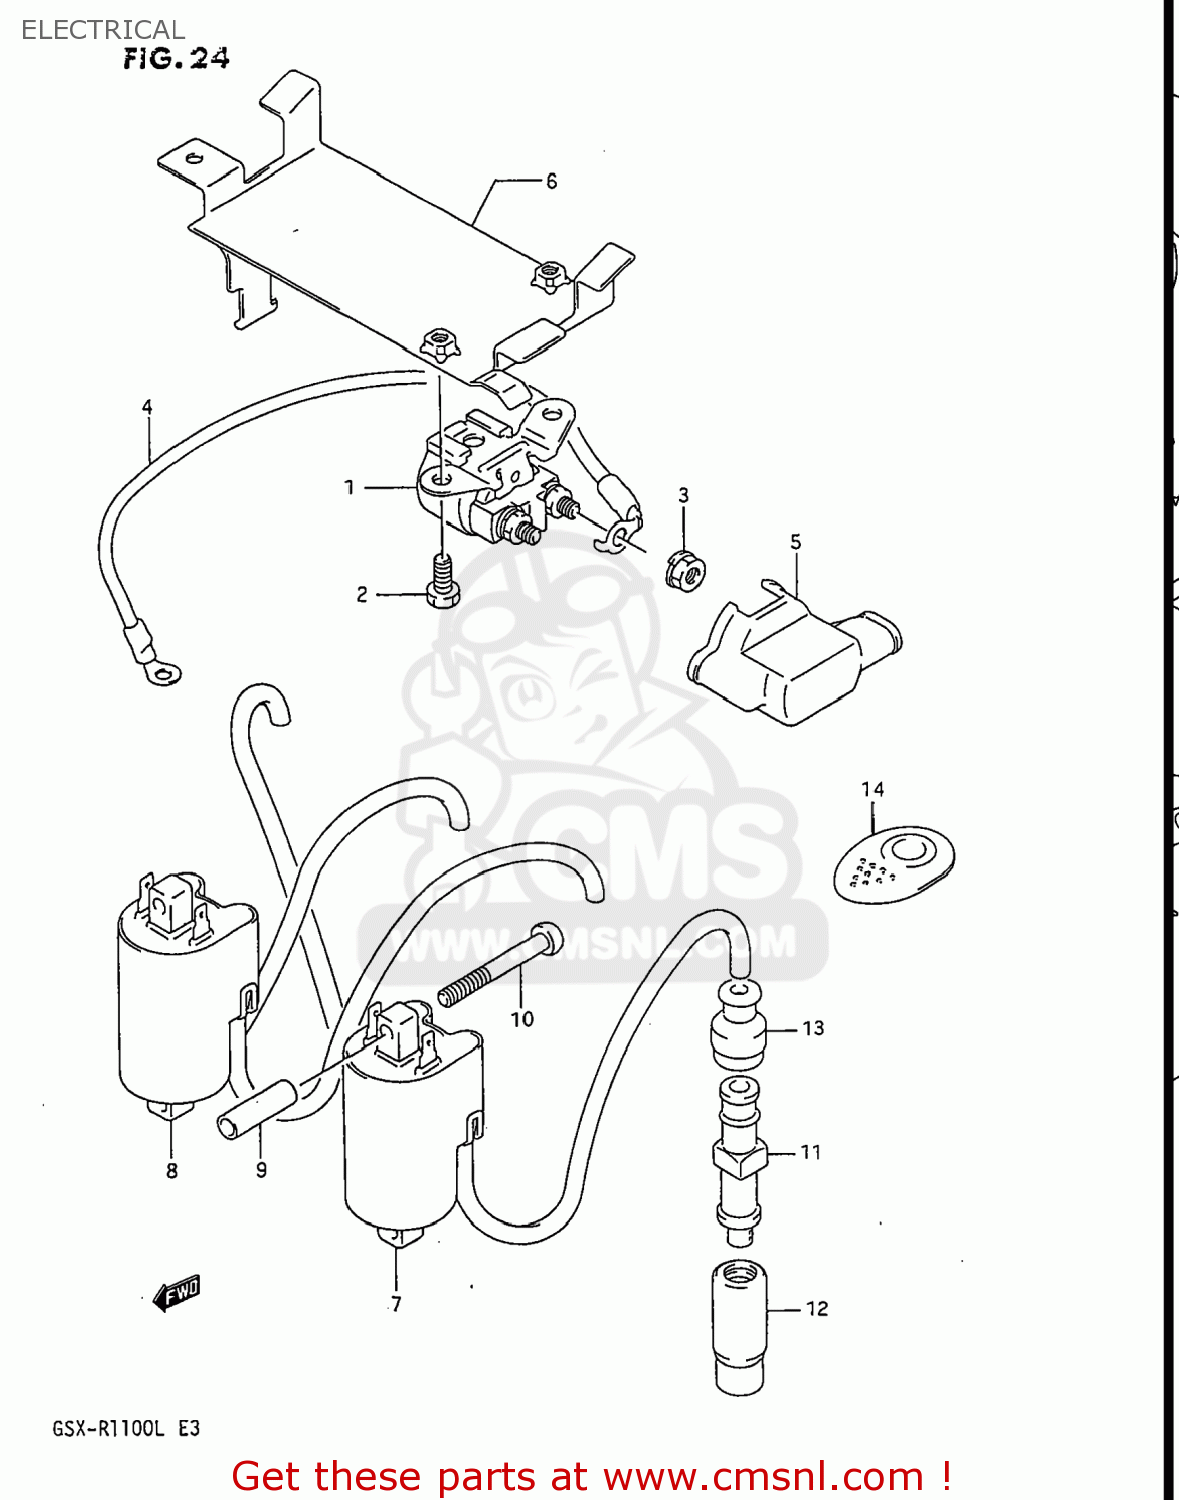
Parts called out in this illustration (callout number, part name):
1	RELAY ASSY,STARTING MOTOR
2	SCREW(6X8)
3	NUT
4	WIRE,STARTER MOTOR LEAD
5	COVER,RELAY ASSEMBLY
6	HOLDER COMP,ELECTRONIC PARTS
7	COIL ASSEMBLY,IGNITION
8	COIL ASSEMBLY,IGNITION
9	SPACER(6.4X10X32)
10	SCREW
11	CAP,SPARK PLUG
12	SEAL,SPARK PLUG
13	SEAL,HIGH TENSION CORD
14	COVER,SPARK PLUG CAP
